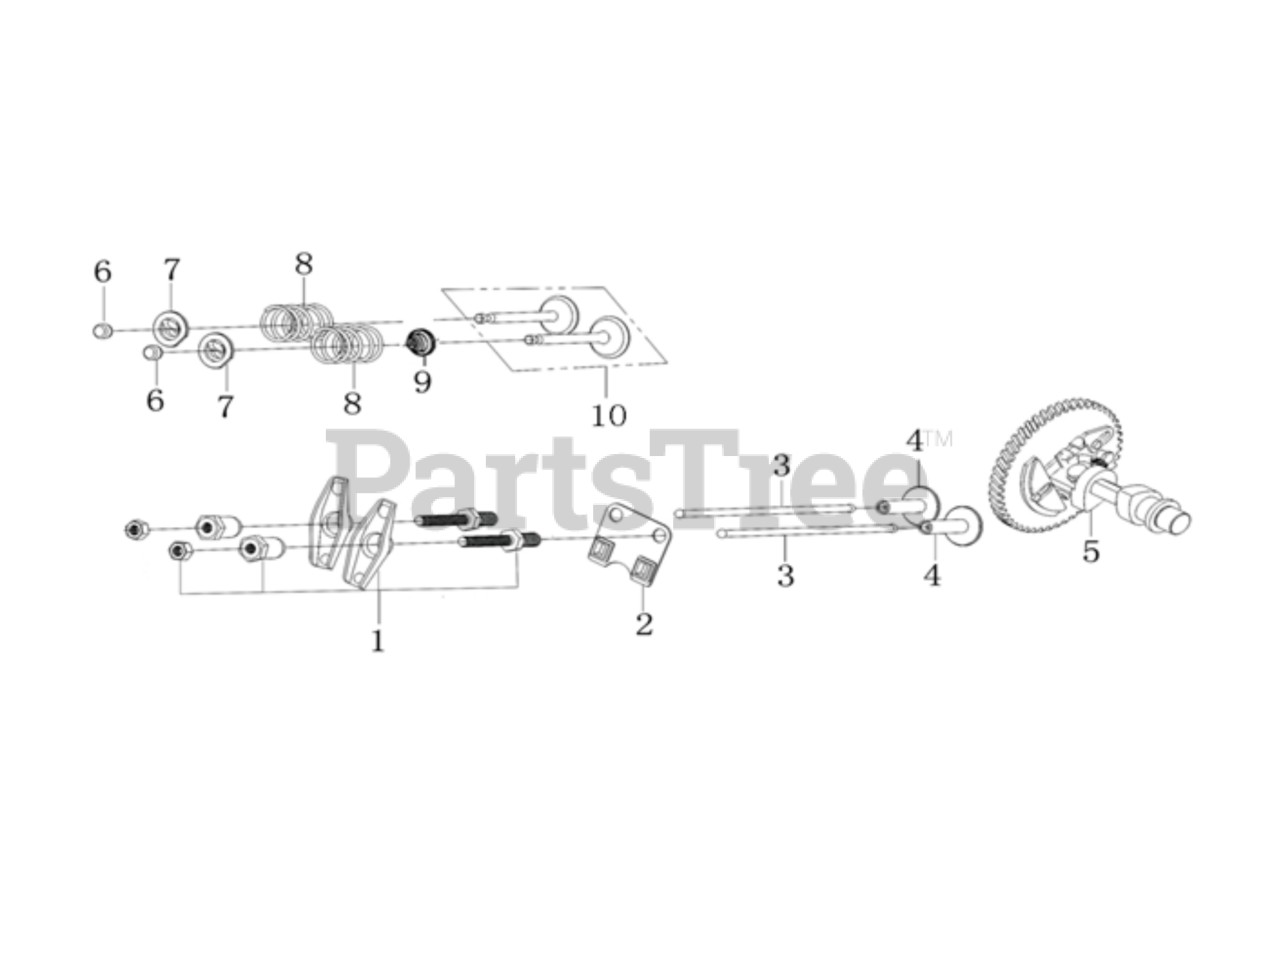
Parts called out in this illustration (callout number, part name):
1	Valve rocker combination
2	Plate, push rod guide
3	Push rod
4	Lifter, Valve
5	Camshaft assy
6	Valve adjustment cap
7	Retainer, valve spring
8	Inner spring of valve
9	Valve oil seal
10	Valve Kit
